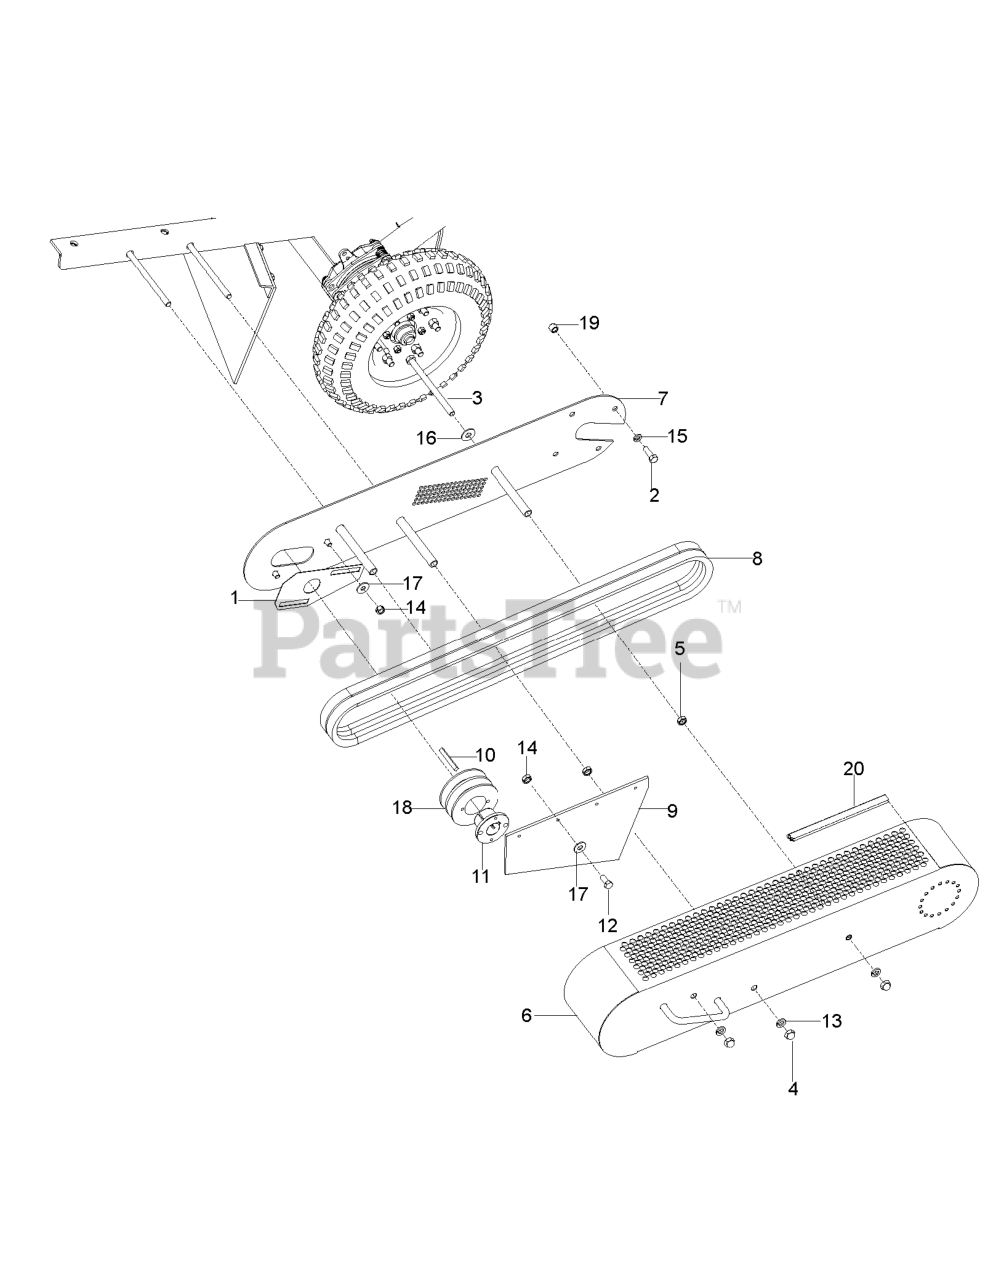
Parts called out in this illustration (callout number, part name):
1	RP CABLE.DRIVE.S/S.22+.FWGD
7	BAIL.CONT.DR.S/S.ROUND.BLACK
11	WHEEL.8X1.75.H3SPK.RAD3.GY.BU3
12	E-RING 7/16 RE
13	PINION.14.TEETH.FGD
14	COVER.DUST.WHEEL.INNER.WALK
15	PAWL, DRIVE
16	WASHER FLUT
18	SELECTOR KNOB
25	BRACKET.BELT.GUIDE.22+FGD.BZP
27	SCREW, HEX HD TAPPING #10-24 1
28	COVER.DRIVE.22.LABEL.HUSQVARNA
29	NUT.HEX.FLANGE.3/8-16.LO(3 2)
32	RP PULLEY.DRIVE.EZ/VAR.SCREWON
33	BELT.DRIVE.FGD.
35	ADJUSTER.ASM.9.22+/RF/LR.21/RF
36	RP.TRANSMISSION.22+.FWGD.SS
38	NUT.HEX.FLANGE.1/4
41	ADJUSTER.ASM.9.22+/RF/LR.21/LF
54	GBAG.A3610247T.SILV.HUSWT.BLUE
57	RB FRAME.GBAG.22PLUS
80	KIT.WASH-OUT.PORT.ZINC.WALK
81	WASHOUT.PORT.ZINC.RGD.22+
82	WASHER.LOCK.INTERNAL.TOOTH
83	LOCKNUT.HEX.WITH.O-RING
84	COUPLING.QUICK CONNECT
